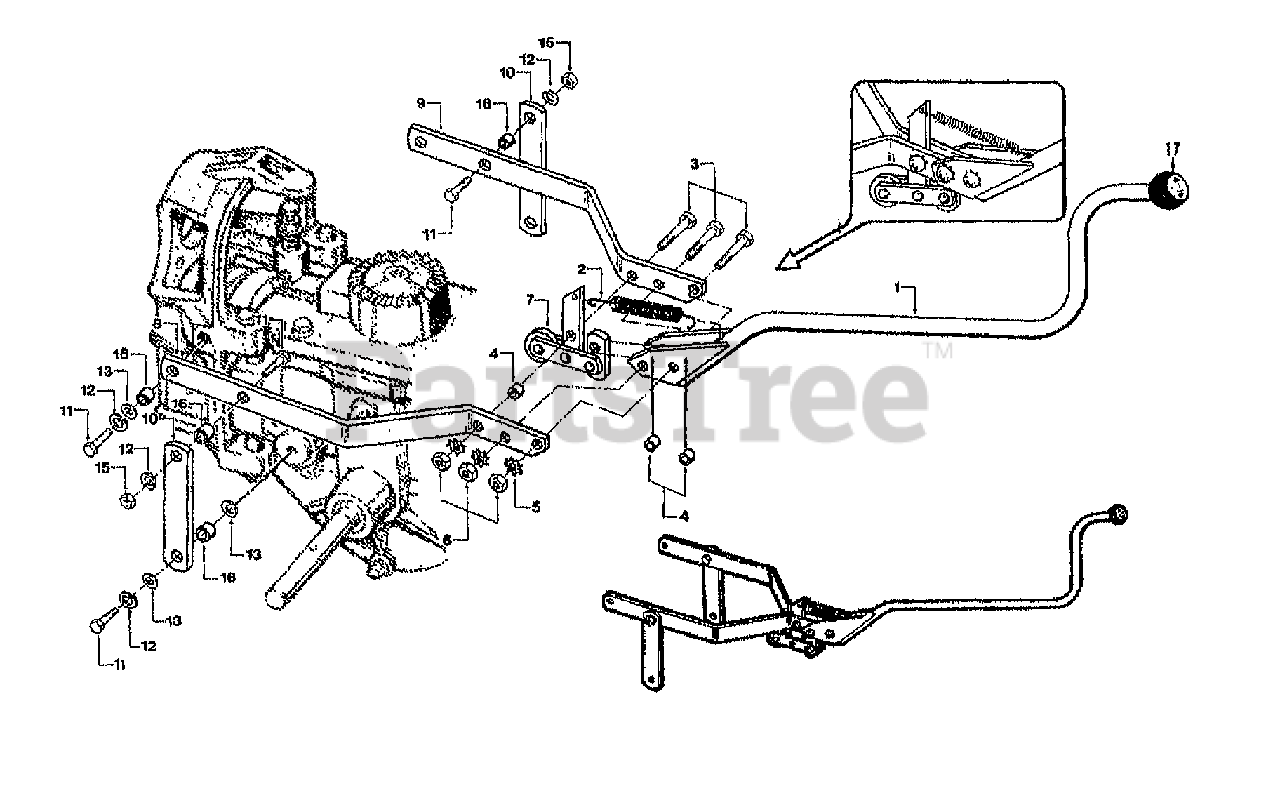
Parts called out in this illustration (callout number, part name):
1	ASSM-FOR/REV LEVER (INCL. KNOB W/DECAL)
2	SPRING-.436 X 3.25
3	SCR-HH 5/16-18X1.5 G5 ZP
4	BUSHING-.5X.316X.375 PM
5	WASHER-LK .312 EXT TOOTH
7	ASSM-ROLLER PAINT
8	YOKE-LH RED
9	YOKE-RH RED
10	YOKE-RED 2164
11	SCR-HH 3/8-16X1.0 G5 ZP
12	WASHER-LK .375 @ DEPL
13	WASHER-FLAT 3/8 SAE
15	NUT-HEX 3/8-16 ZP
16	BUSHING-.5X.375X.3 (.300")
17	KNOB - NOT AVAIL. SEPARATELY. SEE REF. NO. 1
